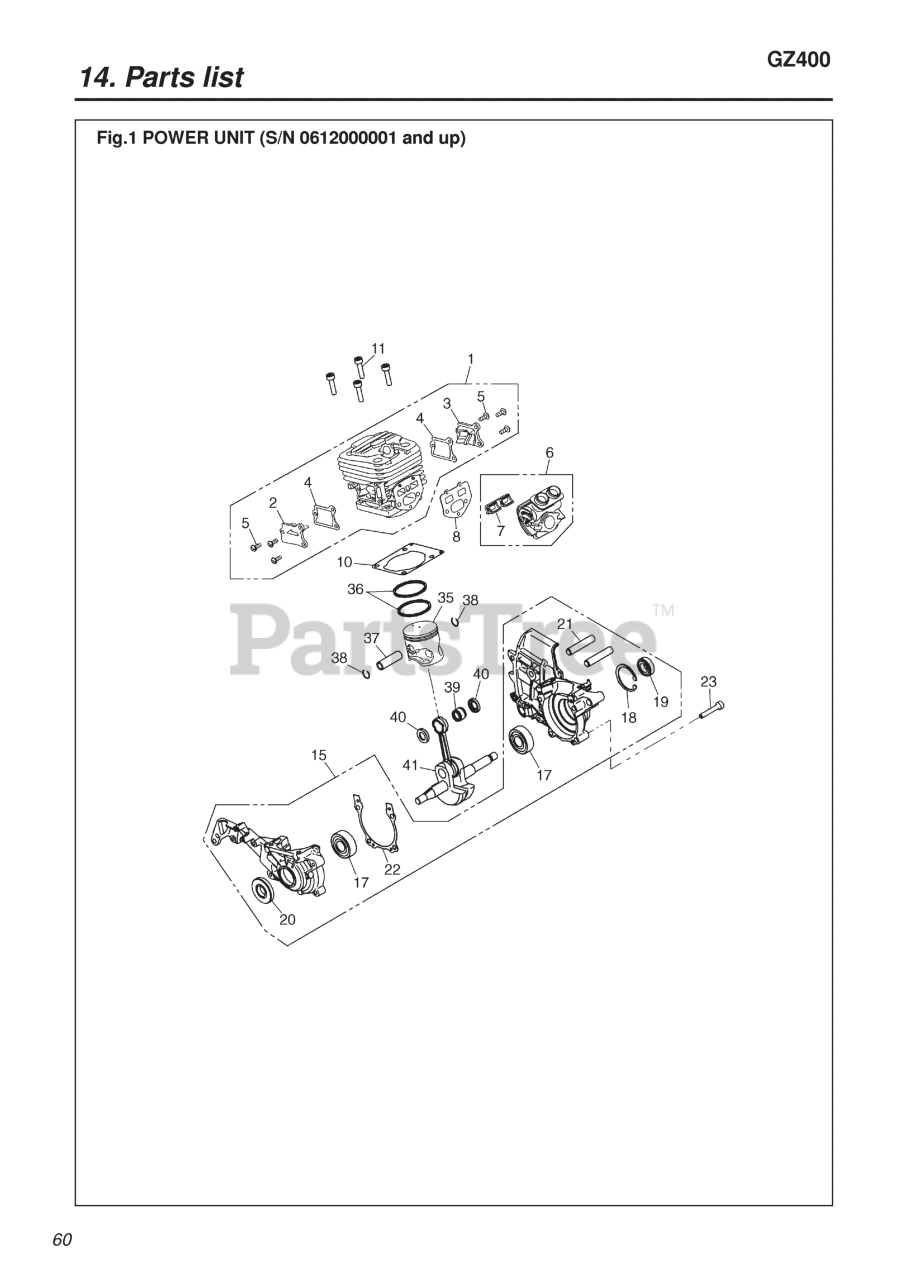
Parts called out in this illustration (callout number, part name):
1	CYLINDER ASSY
2	TR COVER MAG
3	TR COVER PTO
4	GASKET
6	INSULATOR ASSY
7	SEAL
8	GASKET
10	GASKET, CYLINDER
11	BOLT (RPLS 2850-14220)
15	CRANKCASE ASSY
17	BEARING
18	RING, SNAP, M32 x 1.2
19	SEAL, OIL (RPLS 1100-21210)
20	SEAL
21	STUD (RPLS 0205-50825)
22	GASKET, CASE
23	BOLT
35	PISTON
36	RING
37	PIN
38	RING, SNAP
39	BEARING
40	WASHER
41	SHAFT COMP
